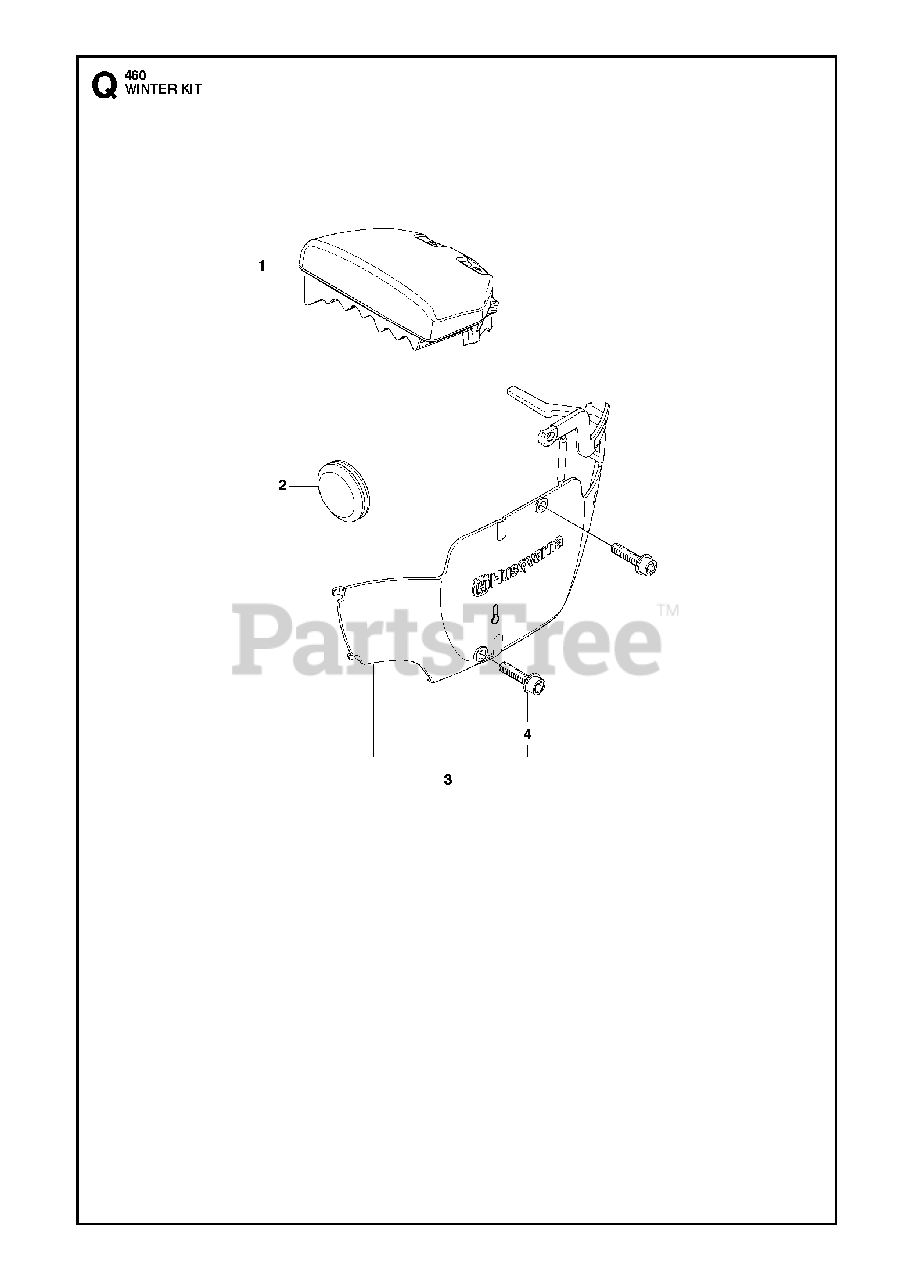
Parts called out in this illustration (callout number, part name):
1	AIR FILTER
3	WINTER SET
4	SCREW
